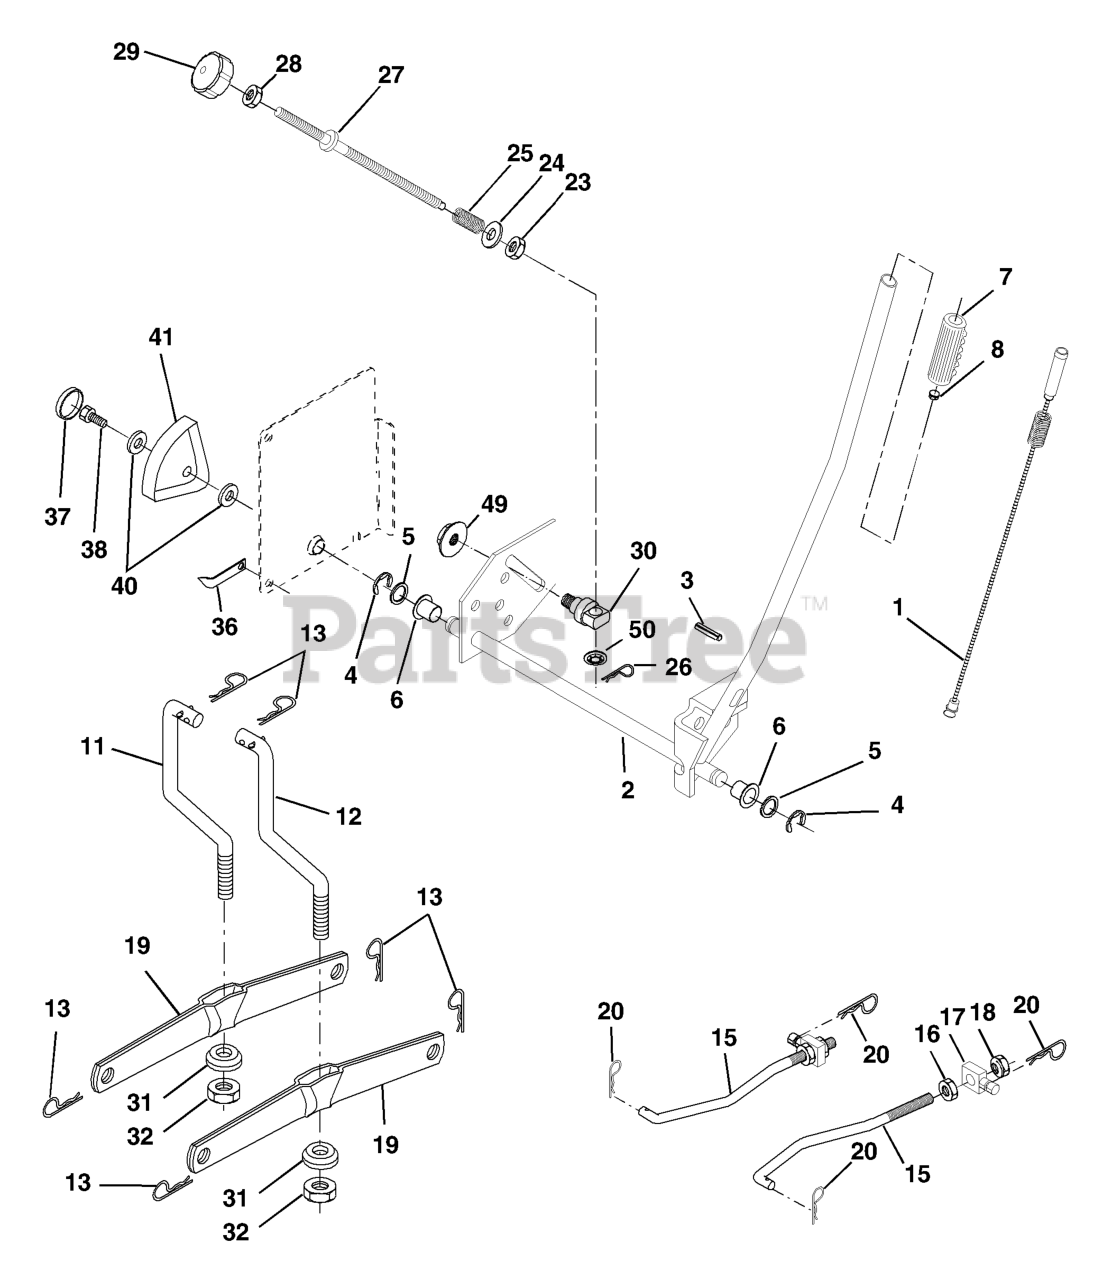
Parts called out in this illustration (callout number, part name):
1	WIRE ASM INNER W/ PLUNGER LT
2	SHAFT ASM R HANDLE
3	PIN GROOVE.
4	RETAINING RING LT
6	BEARING.NYLON
7	GRIP HANDLE
8	PLUNGER BUT KIT
11	LINK
12	LINK
13	RETAINER-SPRNG RB
15	LINK.SUSPENSION.FRONT
16	NUT.HEX.JAM.1/2-13
17	TRUNION
18	NUT.LK.W/WSH.1/2.
19	ARM.REAR.SUSPENSION
20	SPRING RETAINER
25	SPRING**
26	RETAINER CLIP
27	ROD ADJ LIFT
28	NUT
29	KNOB INF 3/8-16
31	BEARING.PIVOT.LIFT
32	NUT CROWNLOCK 3/8-24
36	POINTER, HEIGHT INDICATOR(2 2)
38	SCREW 5/16-18X1
41	HEIGHT INDICATOR
49	NUT
50	NUT PUSH M
